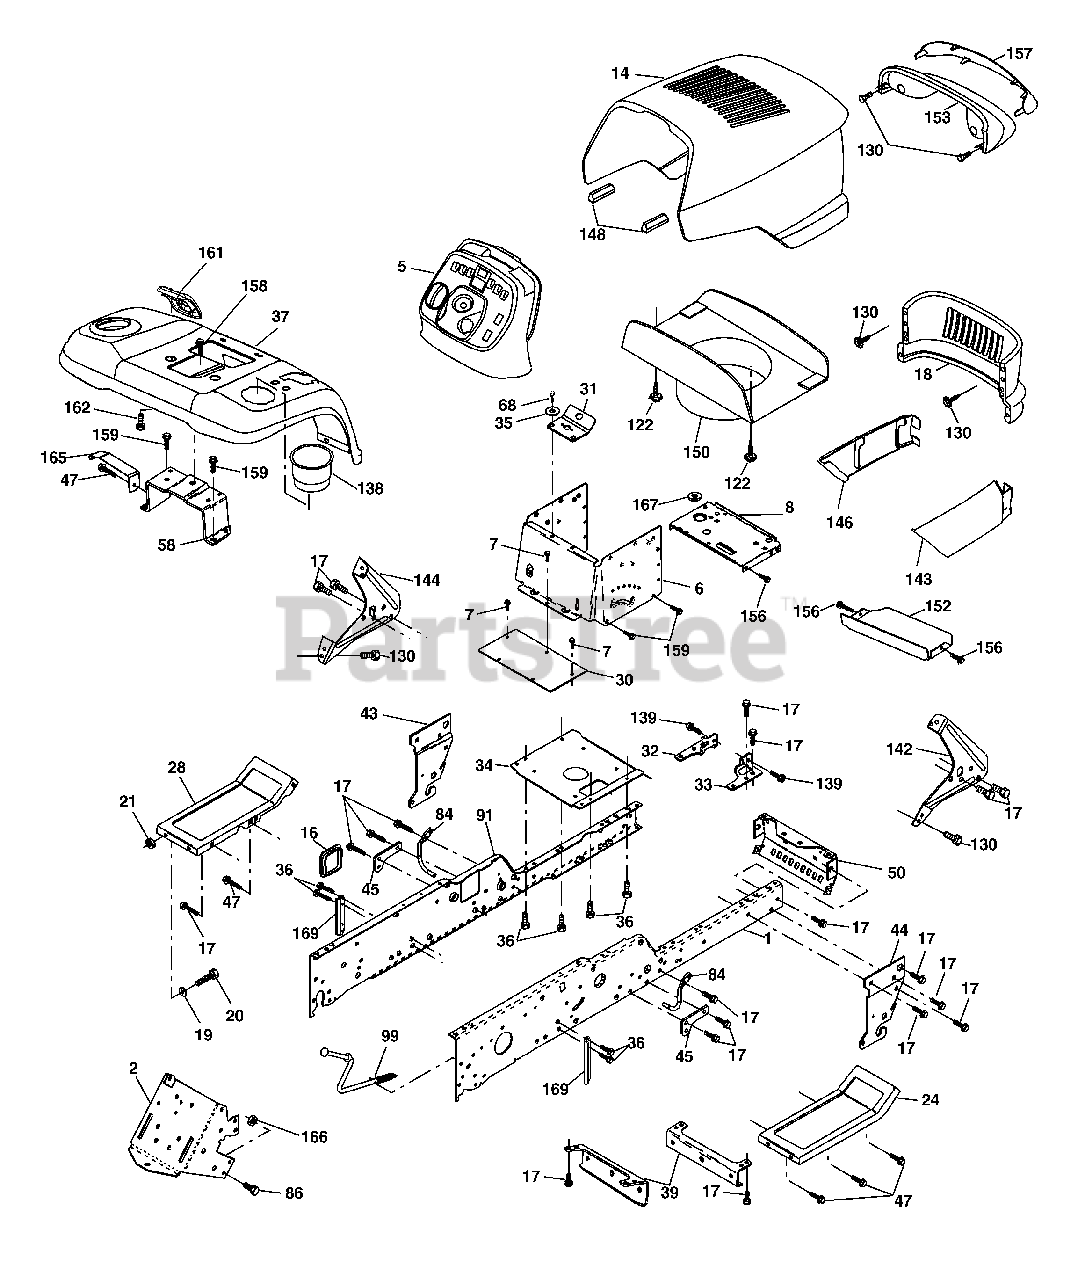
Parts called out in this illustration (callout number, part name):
1	Rail, Frame RH
2	Drawbar, Gt
5	Dash
6	Dash Asm., Lower
7	Screw, Thd Cut 1/4-20 x 1/2
8	Support, Battery
14	Hood Asm., Pnt
16	Cover, Access
17	Screw, 3/8-16 x 3/4
18	Grille
19	Washer 13/32 x 13/16 x 12 Ga.
20	Bolt, Fin Hex 3/8-16 x 1
21	Nut, Lock Hex w/Ins. 3/8-16 unc
24	Footrest, RH
28	Footrest, LH
30	Saddle, Hydro 1995
31	Bracket, Supt 1-pc VGT Steering
32	Bracket, Pivot Chassis LH
33	Bracket, Pivot Chassis RH
34	Plate Asm. Engine Chassis
35	Washer 11/32 x 11/16 x 16 Ga.
36	Screw 5/16-18 x 3/4
37	Fender, Pnt.
39	Bracket, Axle Front
43	Bracket, Spnsn Front Lh
44	Bracket, Spnsn Front Rh
45	Bracket Arm Susp.
47	Screw Thdrol 3/8-16 x 1/2 TYT
50	Bracket, Chassis Front
58	Bracket Asm., Fender
68	Screw, Thd 5/16-18 x 1/2
84	Upstop
86	Bolt, Fin Hex 7/16-14 unc x 1
91	Rail, Frame Lh
99	Rod By Pass
122	Screw Hex Wshd 8-18 x 7/8
130	Screw HWHD Hi-Lo #13-16 x 3/4
138	Cupholder YTGT
139	Bolt Shoulder 5/16-18 TT
142	Bracket Dash RH
143	Skirt Grill RH
144	Bracket Dash LH
146	Skirt Grill LH
148	Extrusion Bumper
150	Duct Heat Hood
152	Shield Browning
153	Light Box Asm. w/Lens
156	Screw 5/16-18 x 3/4
157	Lens, Bar
158	Screw Thdrol 3/8-16 x 1/2
159	Screw 3/8-16 x 3/4
161	Console Fuel Window
162	Screw 1/4-1/2
165	Bracket Support Tank
166	Nut, Crownlock 7/16-14 unc
167	Bushing
169	Bracket Chassis Sway
